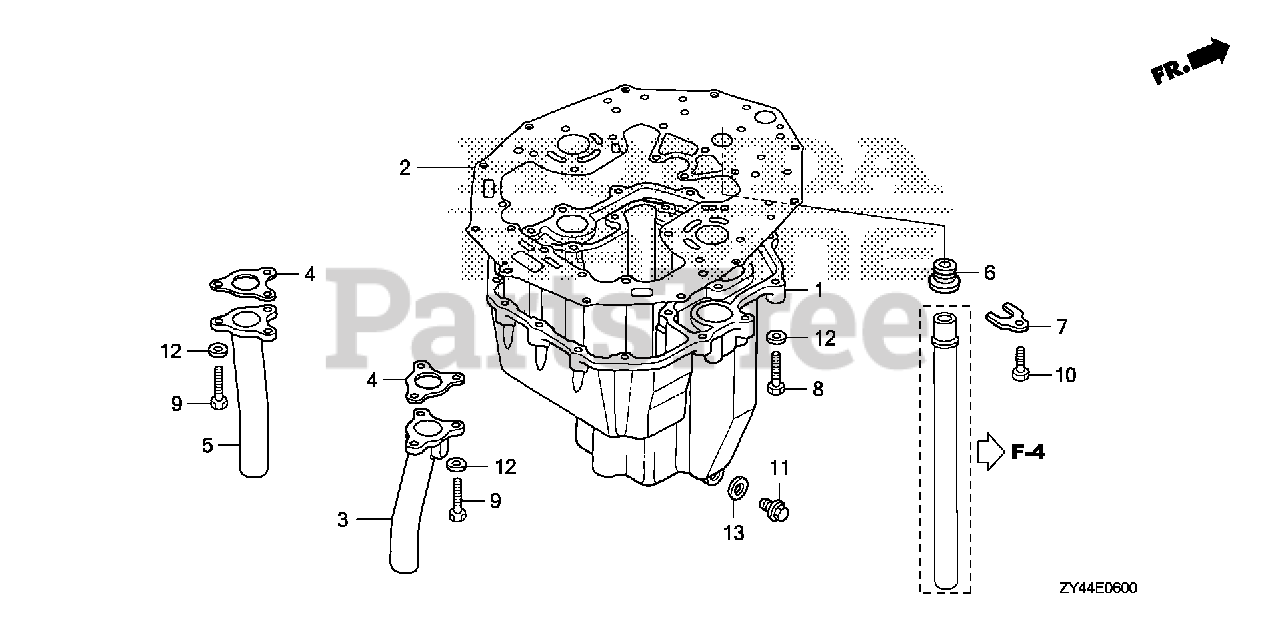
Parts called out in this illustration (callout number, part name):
1	PAN, OIL *TGRAY* (GRAY)
2	GASKET, OIL PAN
3	PIPE, R. EX.
4	GASKET, EX. PIPE
5	PIPE, L. EX.
6	GROMMET, WATER TUBE
7	PLATE, WATER TUBE
8	BOLT, HEX. (8X35)
9	BOLT, HEX. (8X28)
10	BOLT, HEX. (6X16)
11	BOLT, DRAIN PLUG
12	WASHER, PLAIN (8MM)
13	WASHER, DRAIN PLUG (12MM)
